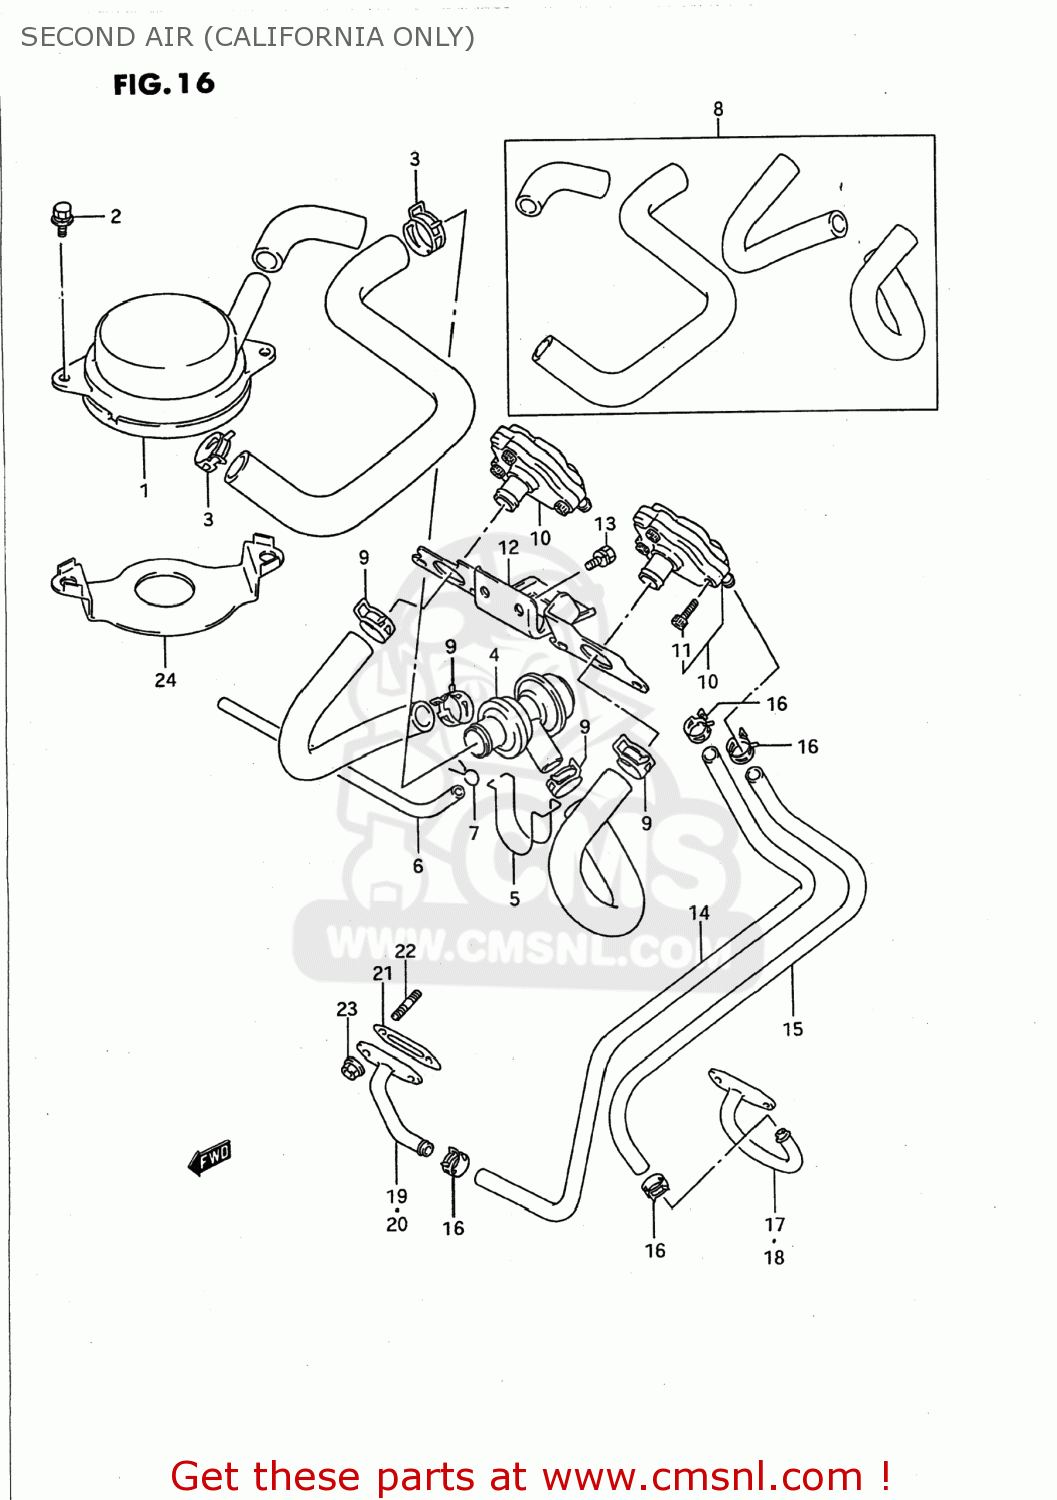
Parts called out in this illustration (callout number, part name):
1	CLEANER ASSEMBLY,SECOND AIR
2	BOLT
3	CLIP
4	VALVE ASSY,AIR SWITCHING
5	CLAMP,SWITCHING VALVE
6	HOSE(4.5X8.5X600)
7	CLAMP
8	HOSE SET,SECOND AIR NO.2
9	CLIP
10	VALVE ASSY,2ND AIR REED
11	BOLT
12	(CA) B/K REED VALVE
13	BOLT
14	HOSE,SECOND AIR NO.1,INLET
15	HOSE,SECOND AIR NO.1,INLET
16	CLIP
17	PIPE,2ND AIR NO.1
18	PIPE,2ND AIR NO.4
19	PIPE,SECOND AIR NO.2
20	PIPE,SECOND AIR NO.3
21	GASKET,SECOND AIR PIPE (NAS)
22	STUD BOLT
23	NUT
24	HOLDER,SECOND AIR CLEANER
